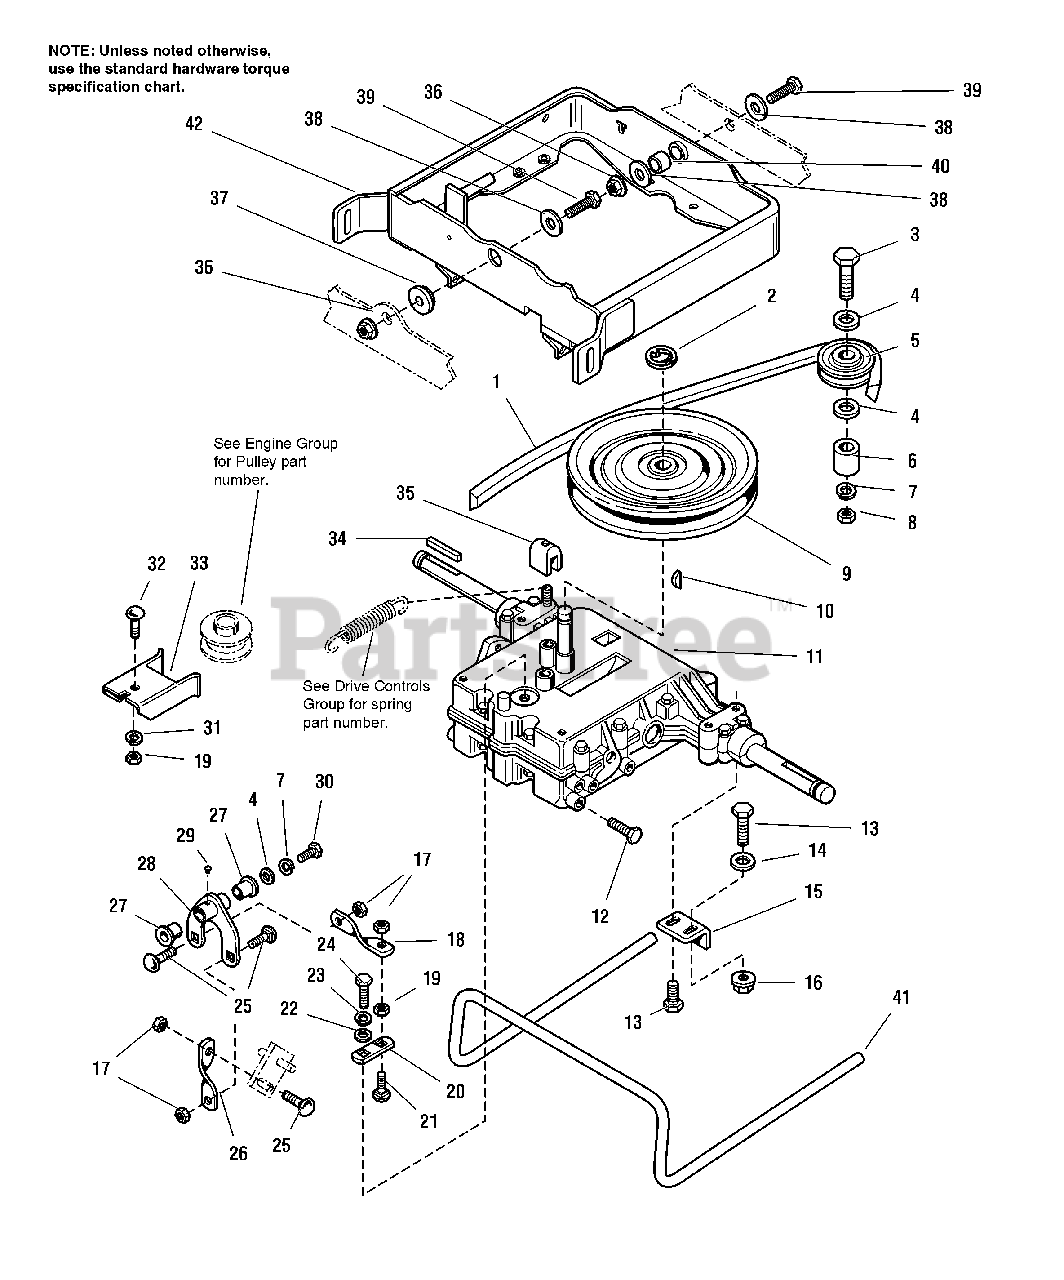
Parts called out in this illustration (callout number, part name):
2	RING, Retaining
3	CAPSCREW, Hex Hd., 3/8-16 x 2, Grade 5
4	WASHER, Plain, 3/8
5	PULLEY, Idler, V
7	LOCKWASHER, 3/8
8	NUT, Hex, Full, 3/8-16
9	PULLEY ASSEMBLY
10	KEY, Woodruff #9
12	CAPSCREW, Taptite Hex Washer Hd, 5/16-18 x 5/8
13	CAPSCREW, Taptite Hex Washer Hd, 5/16-18 x 2-1/2
14	WASHER, 5/16
15	ANCHOR, Torsion Bar
16	NUT, Hex, Flange Whiz Lock, 5/16-18
17	NUT, Hex Nylon Lock, 5/16-18
18	LINK, Shift, Lower
19	NUT, Hex, Full, 5/16-18
20	LEVER, Shift
21	CARRIAGE BOLT, 5/16-18 x 1-1/2
22	WASHER, Plain, 1/4
23	LOCKWASHER, 1/4
24	CAPSCREW, Hex Hd, 1/4-28 x 5/8
25	CARRIAGE BOLT, 5/16-18 x 1-1/4
26	LINK, Shift, Upper
27	BUSHING, Plastic, 5/8
28	BELLCRANK ASSEMBLY
29	FITTING, Grease
30	CAPSCREW, Hex Hd., 3/8-16 x 3/4
31	LOCKWASHER, 5/16
32	CARRIAGE BOLT, 5/16-18 x 3/4
33	GUARD, Belt
34	KEY
35	SPEED NUT, Tinnerman, M6-1
36	NUT, Hex Flange Hd, 1/2-13, 2-Way Lock
38	WASHER, 1/2
39	CAPSCREW, Hex Hd, 1/2-13 x 1-1/2
41	TORSION BAR
42	CARRIER, Transmission, Gear
